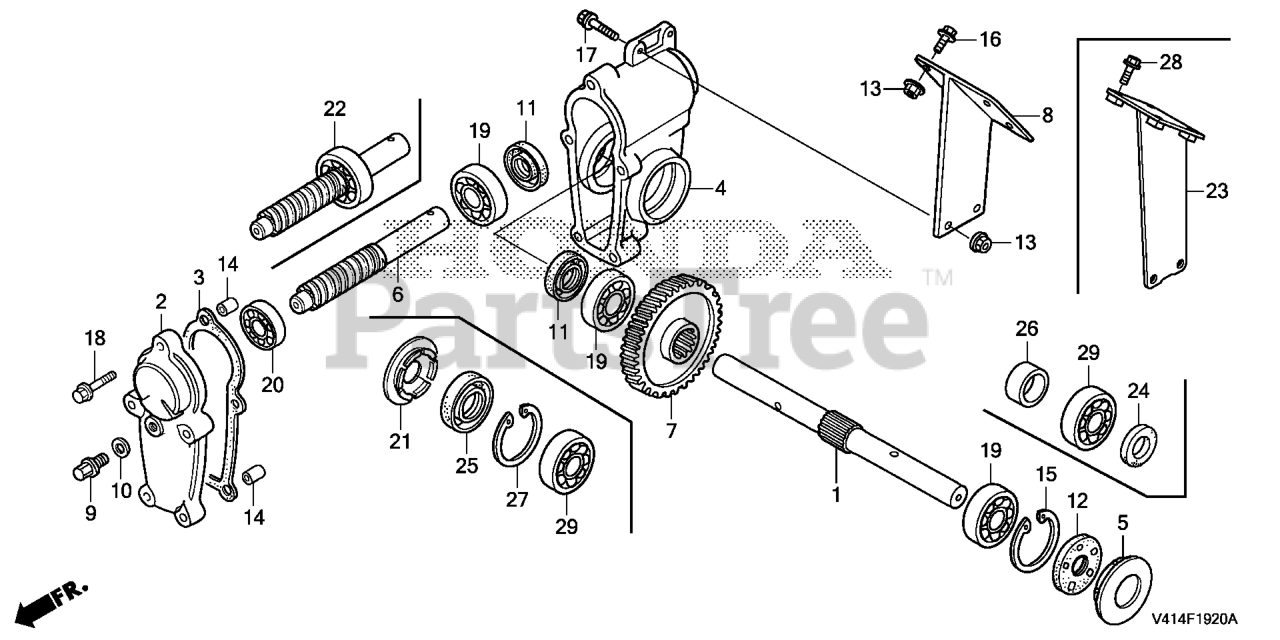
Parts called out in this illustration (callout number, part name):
1	SHAFT, AUGER
2	COVER, AUGER TRANSMISSION
3	GASKET, AUGER TRANSMISSION
4	CASE, AUGER TRANSMISSION
7	GEAR, DRIVEN (55T)
9	BOLT, DRAIN PLUG
10	WASHER, DRAIN PLUG (10.2MM)
11	OIL SEAL (20X32X7)
13	NUT, FLANGE (8MM)
14	PIN A, DOWEL (8X14)
17	BOLT, FLANGE (8X25)
18	BOLT, FLANGE (6X32)
20	BEARING, RADIAL BALL (6202)
21	CAP, AUGER CASE
22	GEAR, DRIVE (6T)
23	BRACKET, AUGER HOUSING
24	OIL SEAL (20X32X7)
25	OIL SEAL (20X42X8)
26	COLLAR, AUGER TRANSMISSION (A)
27	CIRCLIP (INNER) (42MM)
28	BOLT, FLANGE (8X18)
29	BEARING, RADIAL BALL (6004)
